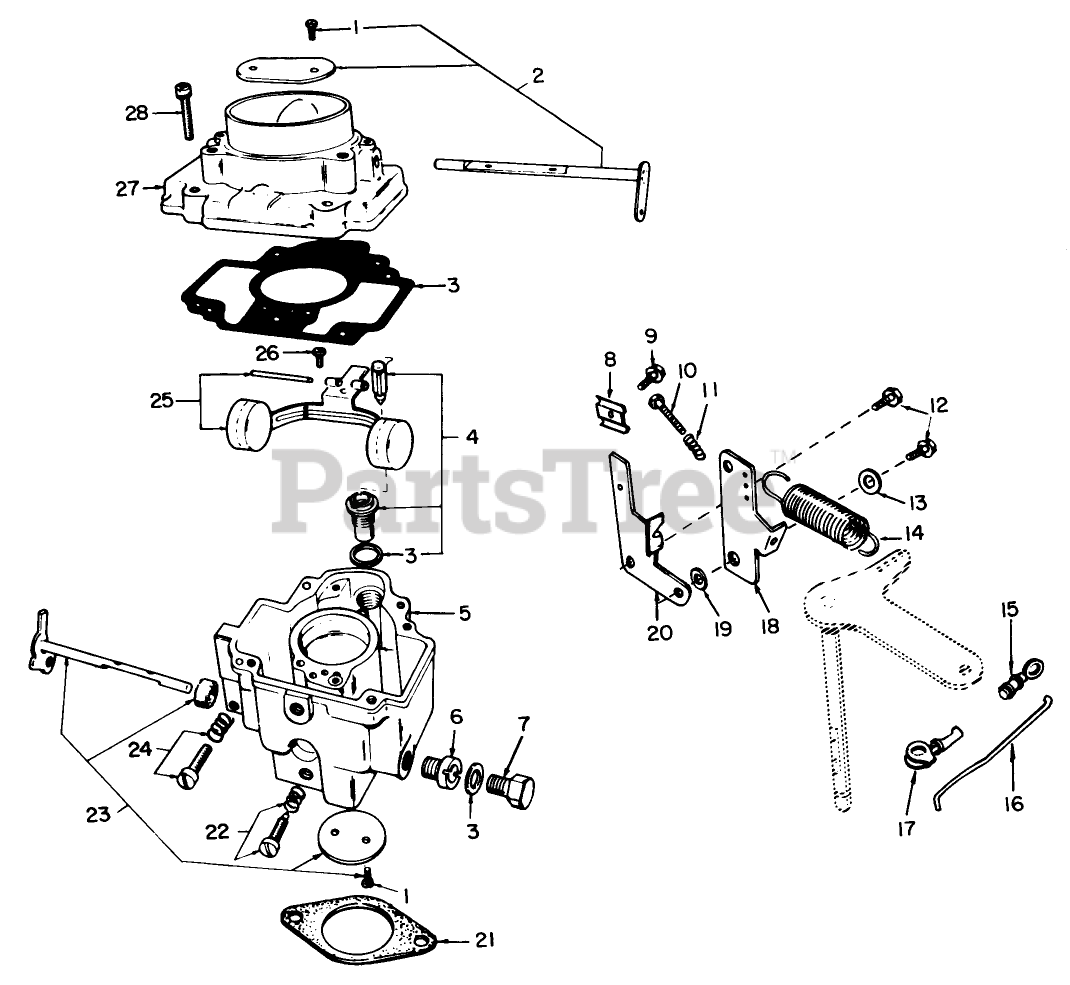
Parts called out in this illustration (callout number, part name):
1	Screw, Valve Mounting
2	Choke Shaft Package
3	Gasket Kit
4	Valve and Seat Package
6	Jet, Power
7	Plug, Power Jet
8	Clamp, Cable
9	Screw, Tapping Hex. Hd.
10	Screw, Tapping Hex Head
11	Spring Idle Setting
12	Screw-Cap Hex Washer Hd.
13	Washer, Flat
14	Spring, Governor
15	Clip, Retaining-Control Rod
16	Rod, Governor Control
17	Clip, Retaining-Control Rod
18	Arm-Governor Control
19	Bushing Control Arm
20	Bracket Cable
21	Gasket Carburetor Mounting
22	Idle Needle Package
23	Throttle Shaft Package
24	Idle Speed Adjusting Screw Pkg.
25	Float Package
26	Screw, Lever Pin
27	Intake, Air
28	Screw, Body to Intake
